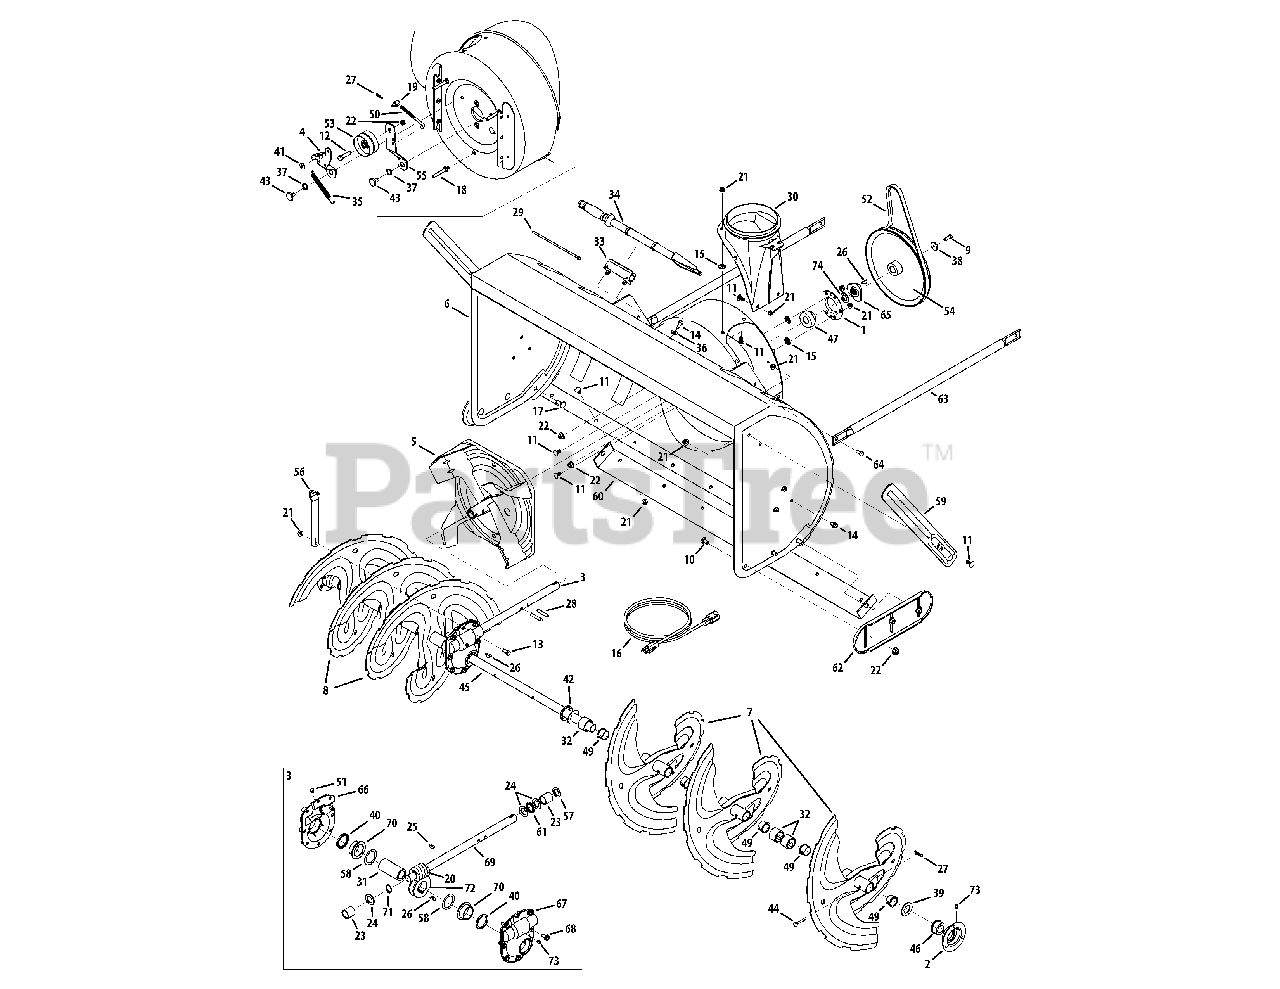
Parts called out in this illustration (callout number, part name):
1	Housing, Bearing
3	Gear Box Assembly, Auger
4	Bracket Assy, Auger Brake
5	Impeller, 16"
6	Housing, Auger - 45"
7	Spiral Assy, LH
8	Spiral Assy, RH
9	Screw, 5/16-24 x .875
10	Bolt, Carriage, 3/8-16 x .750
11	Screw, Carriage, 5/16-18 x .75
12	Screw, Hex Cap, 3/8-16 x 1.75
13	Screw, Hex Cap, 5/16-18 x 1.00
14	Screw, 5/16-18 x .750
15	Nut, Push
16	Extension Cord, 110V
17	Bolt, Carriage, 3/8-16 x 1.0
18	Screw, 5/16-18 x .4300
19	Ferrule
20	Gear, Worm, Dbl Thread
21	Nut, Flnge Lk, 5/16-18
22	Nut, Flg Lk, 3/8-16
23	Sleeve
24	Washer, Flat, .88 ID x .38 OD
25	Key, Hi Pro, 3/16 x 3/4
26	Key, Woodruff,1/4 x 3/4
27	Pin, Bowtie Cotter
28	Pin, Spirol, 5/16 x 1.75
29	Tie, Cable
30	Adapter, Chute, 6"
31	Shaft, Gear, Worm
32	Spacer, 1.0 x 1.5 x 1
33	Clip, Mounting
34	Tool, Cleanout
35	Spring, Extension
36	Washer, .349 x .879 x .063
37	Washer, .625 x .885 x .015
38	Washer, Flat, .34 x 1.50 x .150
39	Spacer, 1.004 x 1.375 x .25
40	Oil Seal
41	Washer, .344 x .75 x .12
42	Washer, 1.01 x 1.86 x .06
43	Screw, Shoulder, .625 x .17
44	Pin, Shear, .25 x 1.75
45	Axle, Spiral, 45"
46	Bearing, Flange w/Flats
47	Bearing, Self Aligning
48	Bushing, Nylon
49	Bushing, Flange, 1.051 x 1.16
50	Rod, Auger Idler
52	V Belt,4L x 44.60" Long
53	Pulley, Flat Idler, 2.75 OD
54	Pulley, Auger Drive, 10.0
55	Bracket, Auger Idler
56	Bracket, Gear Box Support
57	Seal, Oil
58	Washer, Flat, 1.52 ID x 2.0 OD
60	Plate, Shave, 45"
61	Bearing, Thrust
62	Shoe, Skid
63	Support Tube
64	Screw, 5/16-18 x .75
65	Pulley, Adapter, .75 Dia.
66	Hsg Assy Auger RH (Inc. 40 & 70)
67	Hsg Assy Auger LH (Inc. 40 & 70)
68	Screw, LD, 5/16-18 x .750
69	Shaft, Drive, Auger
70	Flange Bearing
71	Ext, Retaining Ring
72	Gear, Worm, LH
73	Lube Fitting, 3/16 #70
74	Washer, .76 x 1.49 x .06
